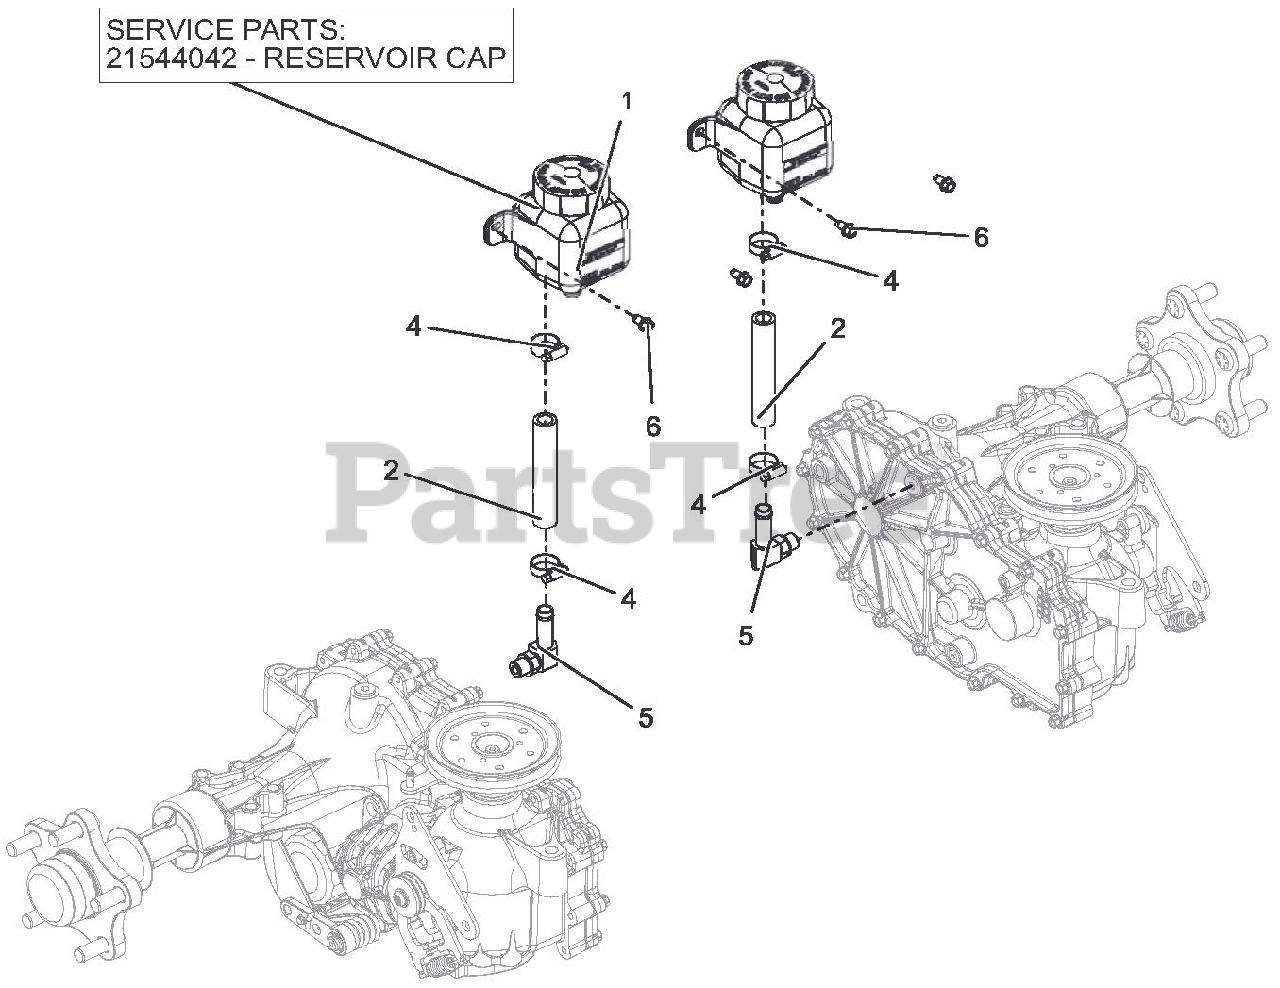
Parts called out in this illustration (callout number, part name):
1	TANK, EXPANSION ZT2800
1	RESERVOIR CAP
2	HOSE, PT100 HYDRO OVERFLOW
4	CLAMP, .88 DIA HOSE
5	FITTING, HYD
6	SCR-TAP .25-20 X .50 HWH TR YWZ
